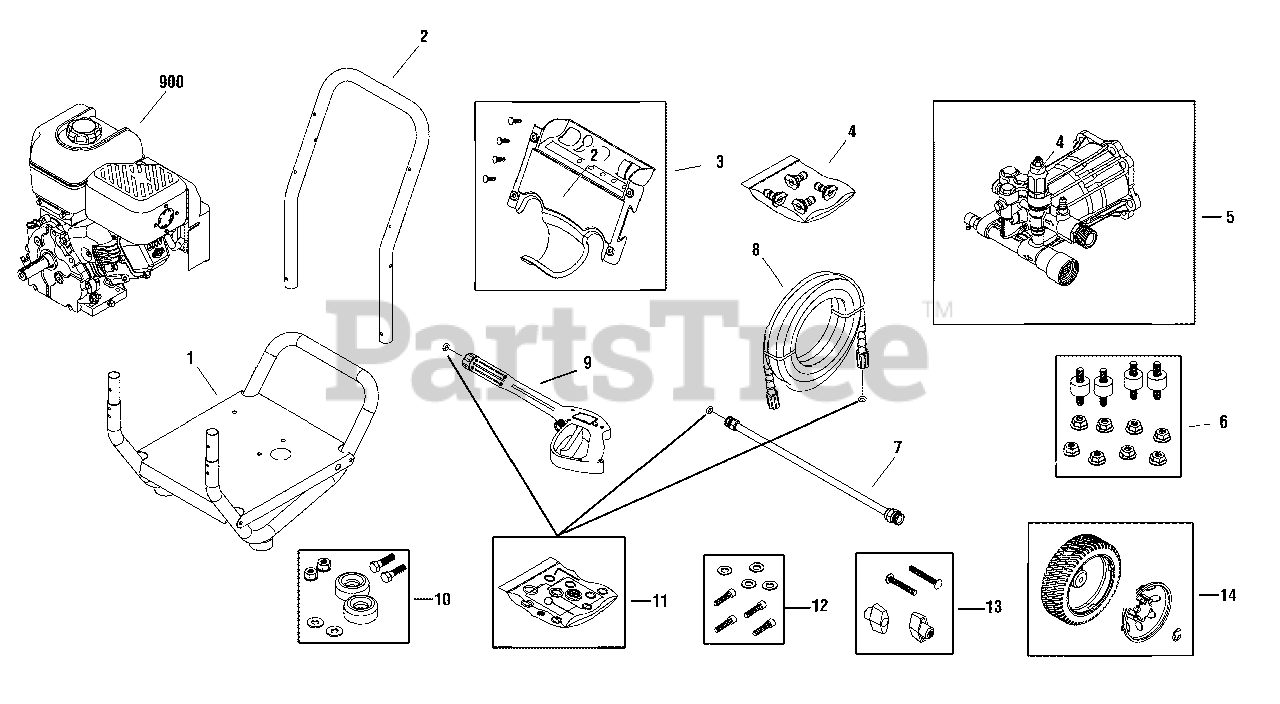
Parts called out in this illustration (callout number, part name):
6	KIT, Vibration Mount
9	GUN
10	MOUNT, Vibration
12	KIT, Hardware, Pump Mounting
13	KIT, Hardware, Handle
900	* ENGINE
